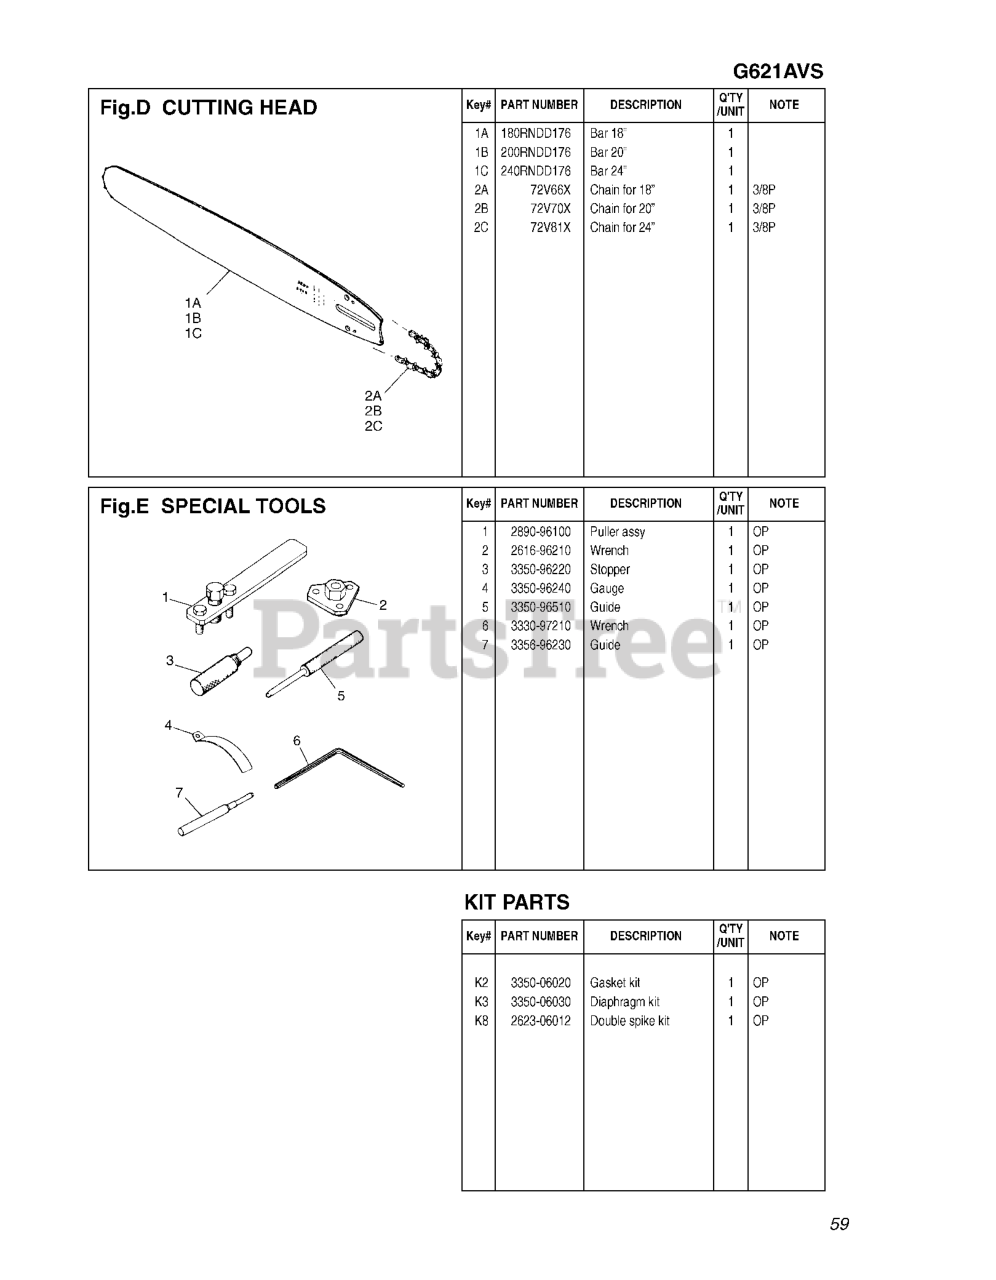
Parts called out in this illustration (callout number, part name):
1	FLYWHEEL PULLER
2	WRENCH.CLUTCH
2A	18" CHAIN (3/8) FOR G621
2B	USE WITH 200RNDD176 BAR
2C	24" CHAIN (3/8) FOR G621
5	GUIDE.PARTONLY
K2	GASKET KIT
K3	DIAPHRAGM KIT
K8	DOUBLE SPIKE KIT
